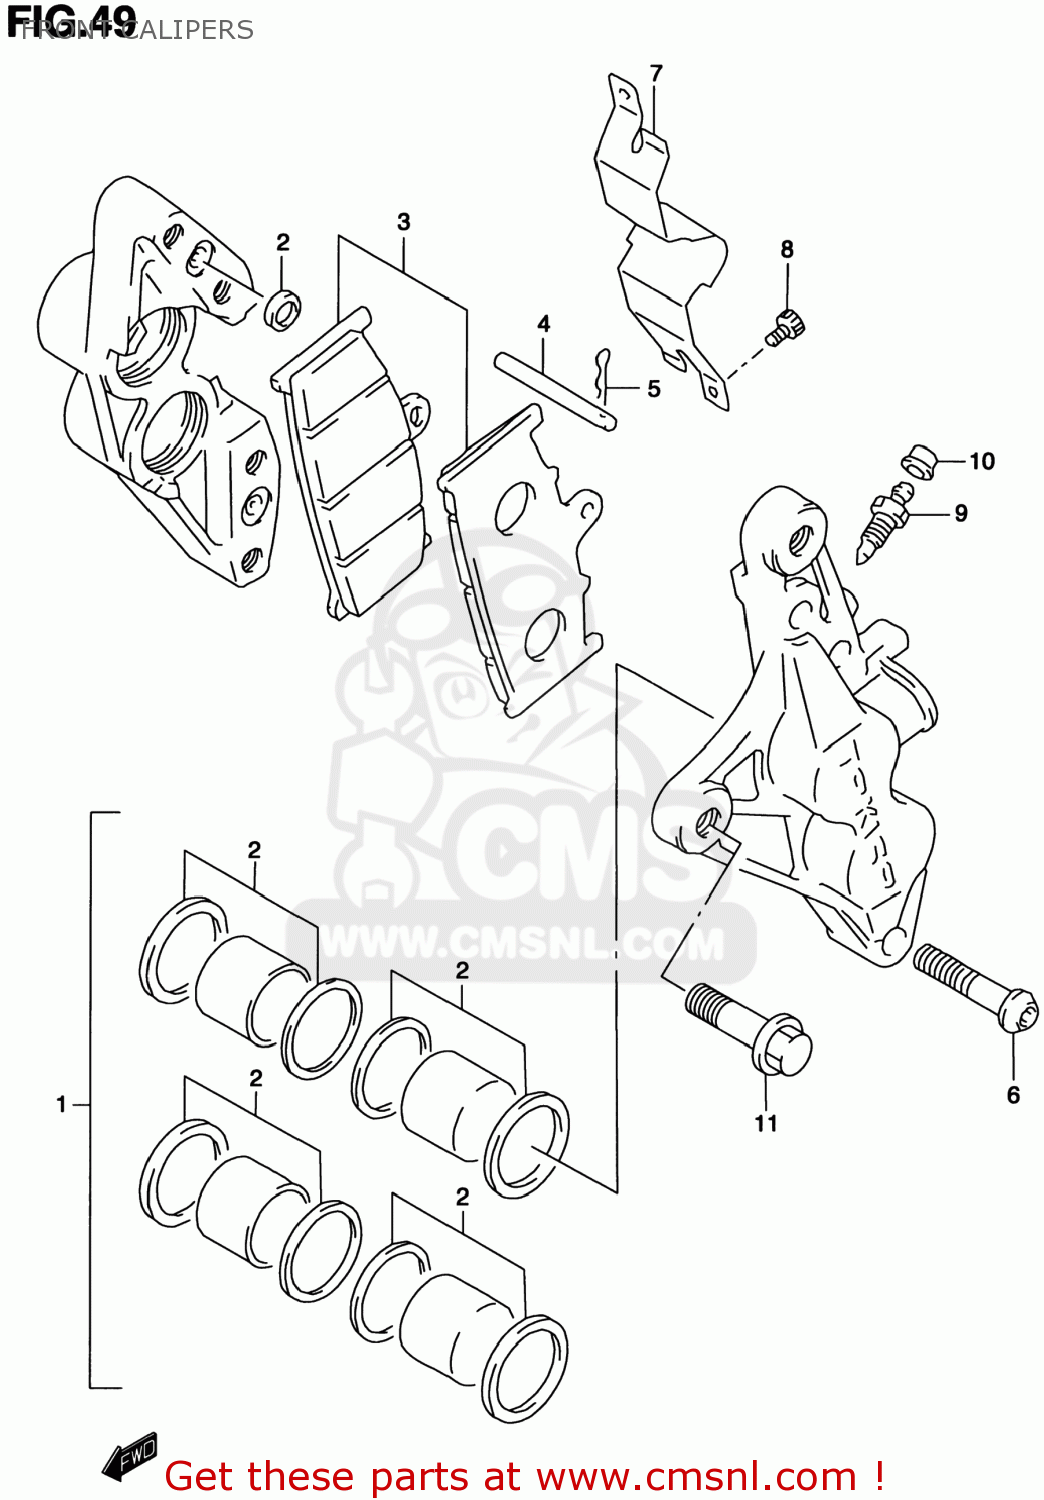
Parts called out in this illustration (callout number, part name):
1	PISTON SET
2	SEAL SET,PISTON
3	PAD SET (NAS)
4	PIN,PAD
5	CLIP,PAD PIN
6	BOLT,HOUSING
7	COVER,CALIPER DUST,R
8	SCREW
9	BLEEDER
10	CAP,BLEEDER PLUG
11	BOLT(10X30)
